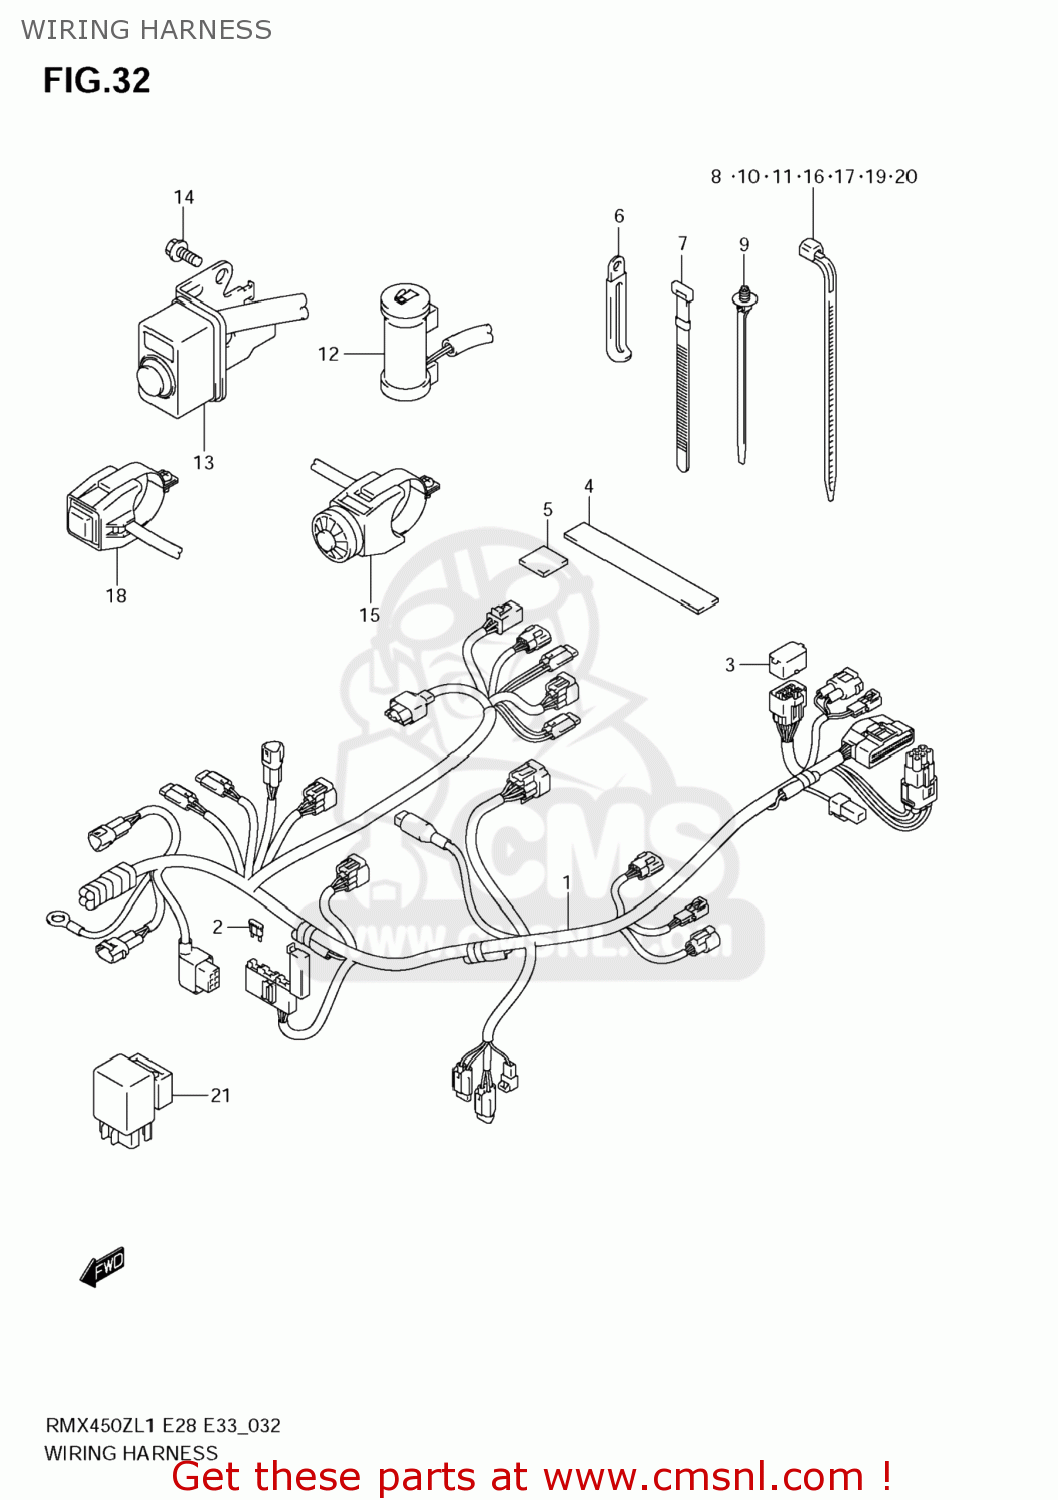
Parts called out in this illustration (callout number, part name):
1	HARNESS,WIRING
2	FUSE(15A)
3	CAP,TS
4	PROTECTOR,WIRING HARNESS
5	PROTECTOR,20X2
6	CLAMP(L:135)
7	CLAMP(L:95)
8	CLAMP(L:125)
9	CLAMP(L:145)
10	CLAMP(L:165)
11	CLAMP(L:235)
12	LAMP ASSY,FUEL
13	SWITCH ASSY,IGNITION
14	BOLT
15	SWITCH ASSY,STARTER MOTOR
16	CLAMP(L:95)
17	CLAMP(L:125)
18	SWITCH ASSY,ENGINE STOP
19	CLAMP(L:95)
20	CLAMP(L:125)
21	RELAY ASSY,HEADLAMP
